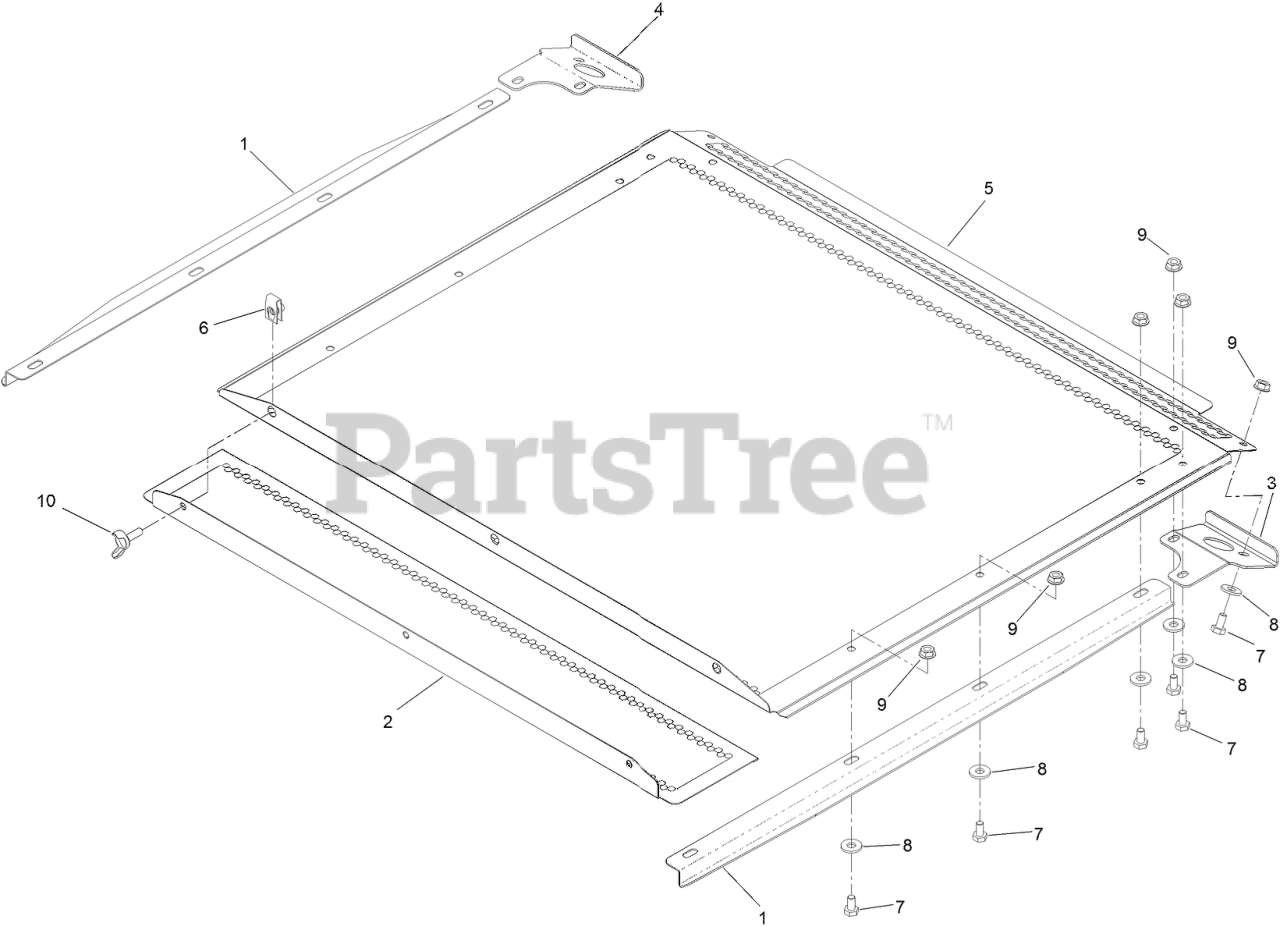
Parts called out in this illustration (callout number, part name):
1	GUIDE-SCREEN
2	PANEL-SCREEN, REMOVABLE
3	HANDLE-SCREEN, LH
4	HANDLE-SCREEN, RH
5	PANEL-SCREEN, HOPPER
7	SCREW-HH
8	WASHER-FLAT
10	SCREW-WING
